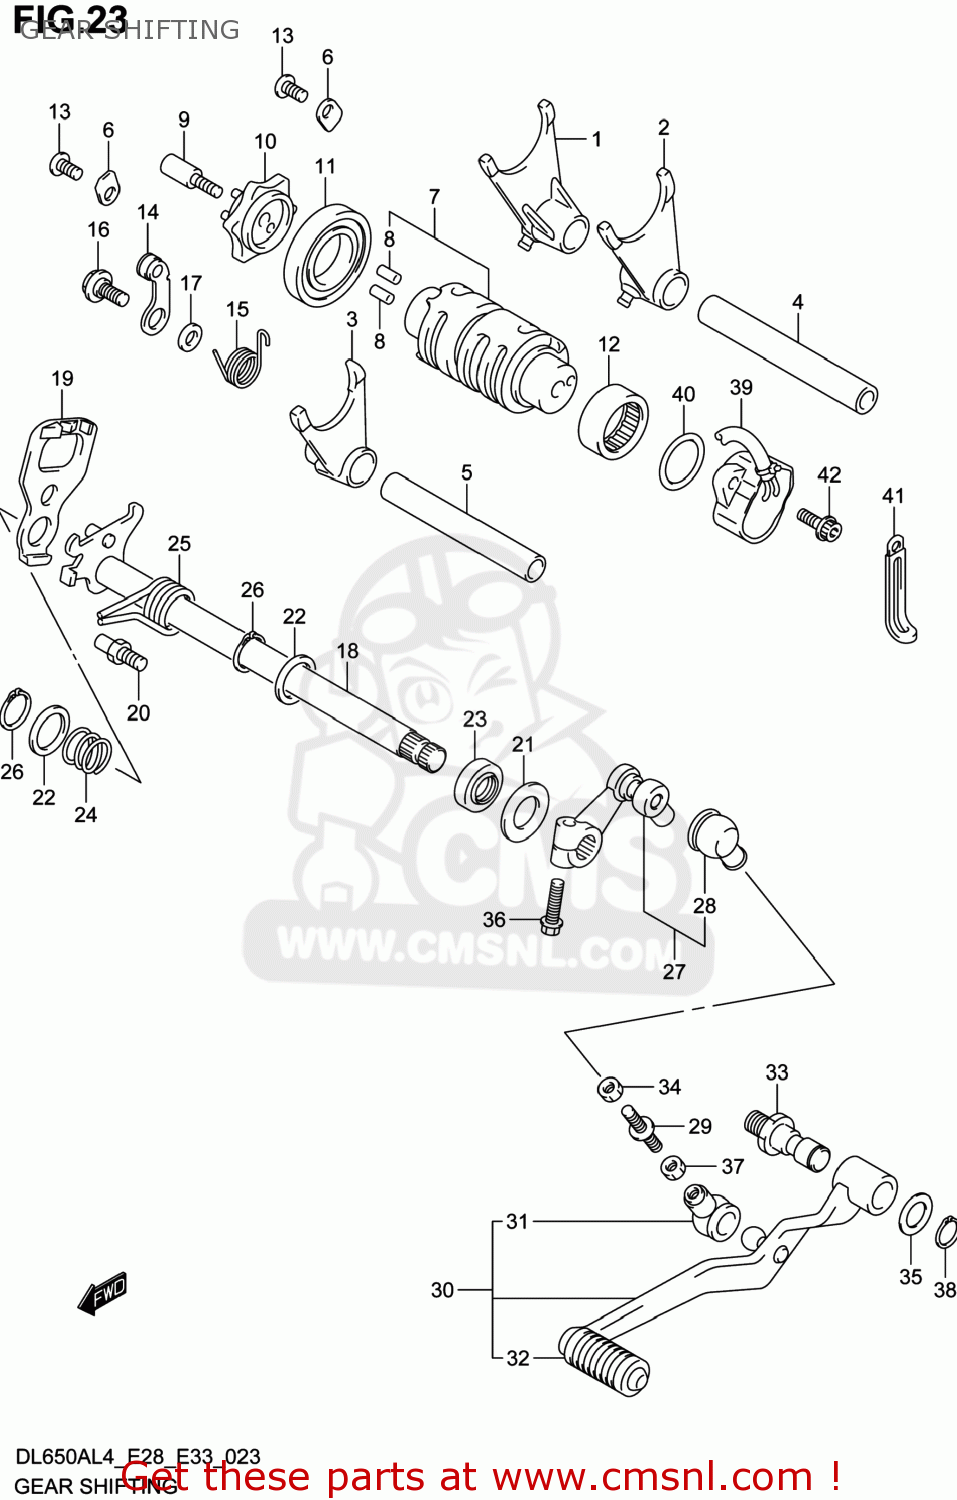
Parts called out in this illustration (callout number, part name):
1	FORK,GEAR SHIFT NO.1
2	FORK,GEAR SHIFT NO.2
3	FORK,GEAR SHIFT NO.3
4	SHAFT,GEAR SHIFT FORK
5	SHAFT,GEAR SHIFT FORK NO.1
6	RETAINER
7	CAM,GEAR SHIFT
8	PIN
9	BOLT,GEAR SHIFT CAM PLATE
10	PLATE,GEAR SHIFT CAM
11	BEARING(25X47X8)
12	BEARING(25X32X12)
13	SCREW
14	STOPPER,SHIFT CAM
15	SPRING,SHIFT
16	BOLT(6X14.3)
17	WASHER
18	SHAFT,GEAR SHIFT
19	PLATE,GEAR SHIFT CAM DRIVE
20	STOPPER,GEAR SHIFT ARM
21	WASHER(14X29X0.8)
22	SHIM(14X22X1)
23	SEAL,OIL(14X22X7.3)
24	SPRING
25	SPRING
26	CIRCLIP
27	ARM,GEAR SHIFT LINK
28	COVER,DUST
29	ROD,GEAR SHIFT LINK
30	LEVER ASSY,GEAR SHIFT
31	COVER,DUST
32	RUBBER,GEAR SHIFT PEDAL
33	SHAFT,GEAR SHIFT LEVER
34	NUT
35	WASHER(12.5X20X1)
36	BOLT
37	NUT
38	CIRCLIP
39	SENSOR ASSY,GEAR POSITION
40	O RING(D:2.4,ID:26.2)
41	CLAMP(L:80)
42	BOLT(5X16)
